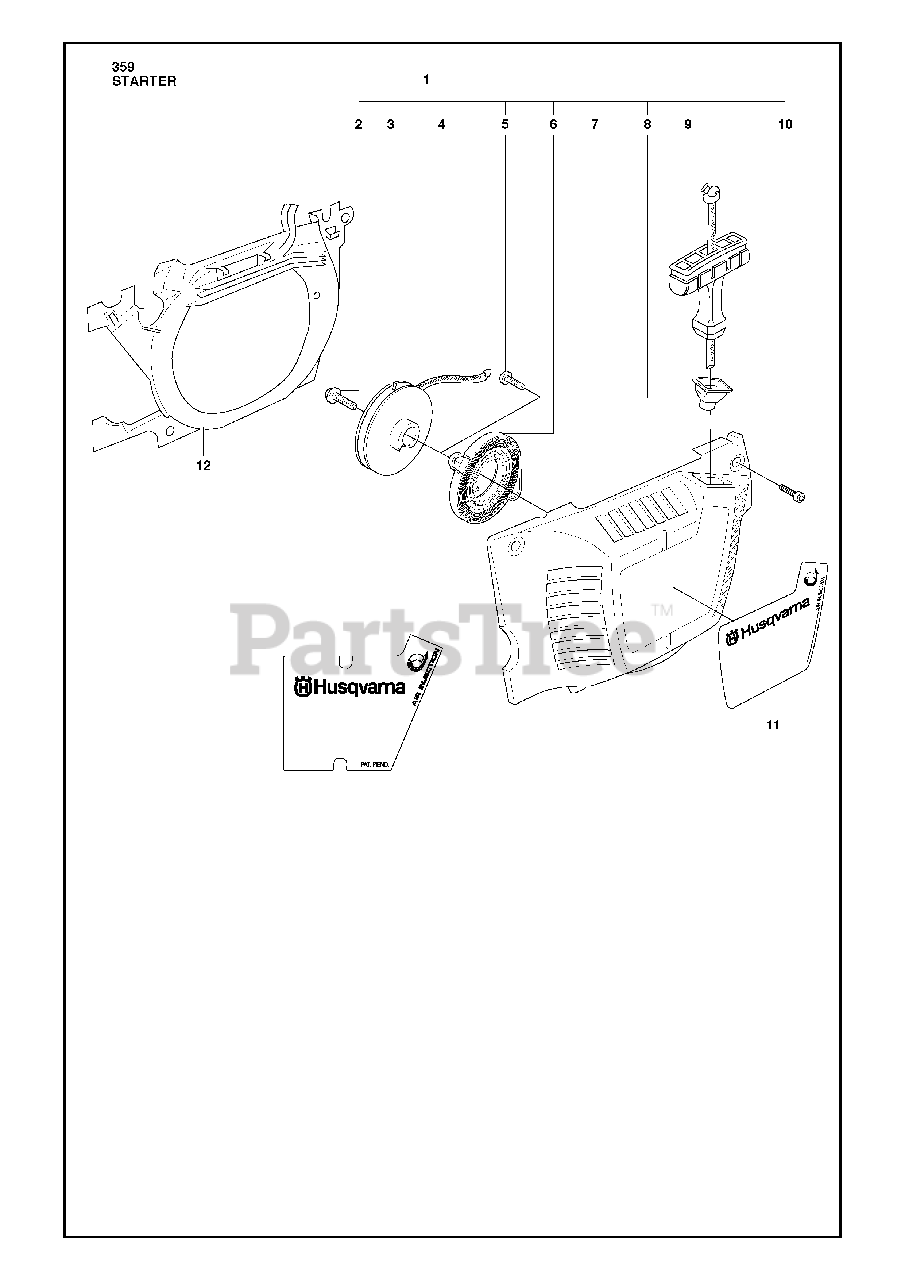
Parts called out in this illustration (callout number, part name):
1	STARTER DEVICE COMPLETE
3	STARTER PULLEY
4	STARTER ROPE
6	RETURN SPRING
7	STARTER HOUSING.
9	STARTER HANDLE
11	DECAL
11	Decal
12	AIR CONDUCTOR
